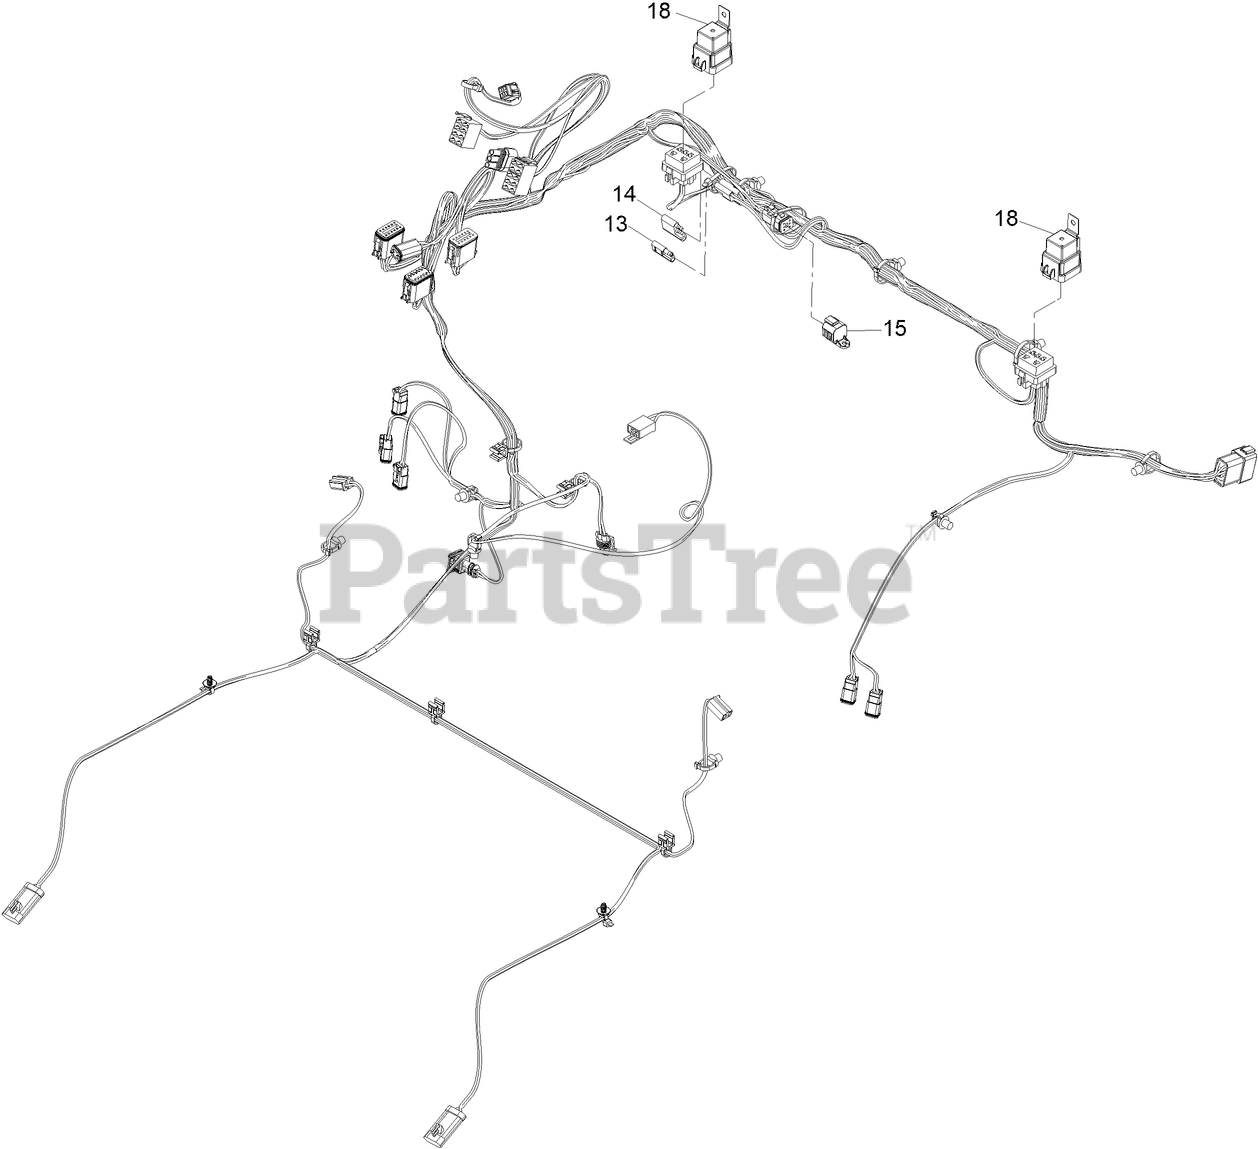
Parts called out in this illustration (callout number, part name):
13	CAP-PLUG
14	CAP-PLUG
15	CAP-PLUG, 6 WAY
18	RELAY-MINI
